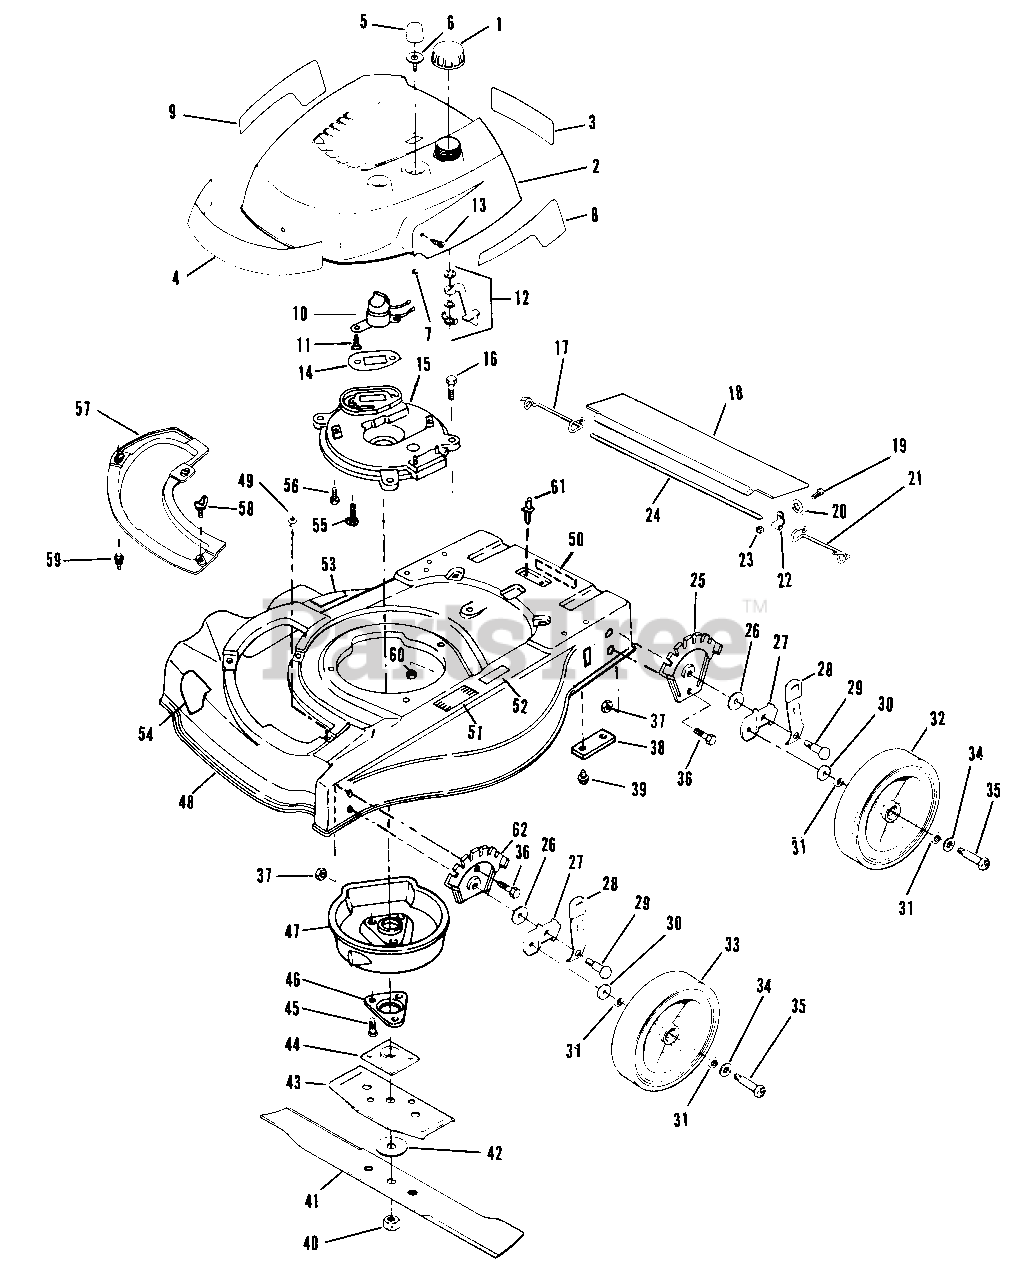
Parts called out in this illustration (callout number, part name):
1	Fuel Cap
2	Shroud-Engine
3	Decal-Instructions
4	Decal-Lawn-Boy
5	Bulb-Primer
6	Base-Primer
7	Nut
8	Decal-L.H. 21"
9	Decal-R.H. 21"
10	Switch Assembly
11	Screw
12	Fuel Shut-Off Assembly
13	Screw Shroud Mounting
14	Gasket-Exhaust
15	Plate-Muffler
16	Screw-Muffler Plate Housing
17	Spring-R.H.
18	Shield-Trailing
19	Screw
20	Washer
21	Spring-L.H.
22	Clamp
23	Nut
24	Rod-Trailing Shield 21"
25	Plate-Height Adjust Rear
26	Washer
27	Bracket-Wheel Height Adjustment
28	Knob & Spring Assembly
29	Shoulder Bolt
30	Washer
31	Washer-Felt
32	Wheel-Rear
33	Wheel-Front
34	Washer
35	Bolt-Wheel
36	Screw-Plate Height Adjustment
37	Nut-Back-Up Plate & Adjustment Bracket
38	Plate-Handle Bracket Screw
39	Screw-Handle Bracket to Housing
40	Nut-Blade
41	Blade
42	Washer-Blade
43	Stiffener-Blade
44	Collar & Plate Assembly
45	Screw
46	Support-Crankshaft
47	Muffler Cover Assembly
48	Housing
49	Grommet
50	Decal-Caution
51	Pad-Starting
52	Decal-Starting Pad
53	Decal-Discharge Area
54	Decal-Blade Contact Warning
55	Screw-Muffler Plate to Block
56	Screw-Muffler Plate to Block
57	Cover Plate
58	Wing Screw
59	Screw-Plate and Chute Mounting
60	Nut-Muffler Plate to Housing
61	Rivet-Serial Plate
62	Plate-Height Adjust-Front
